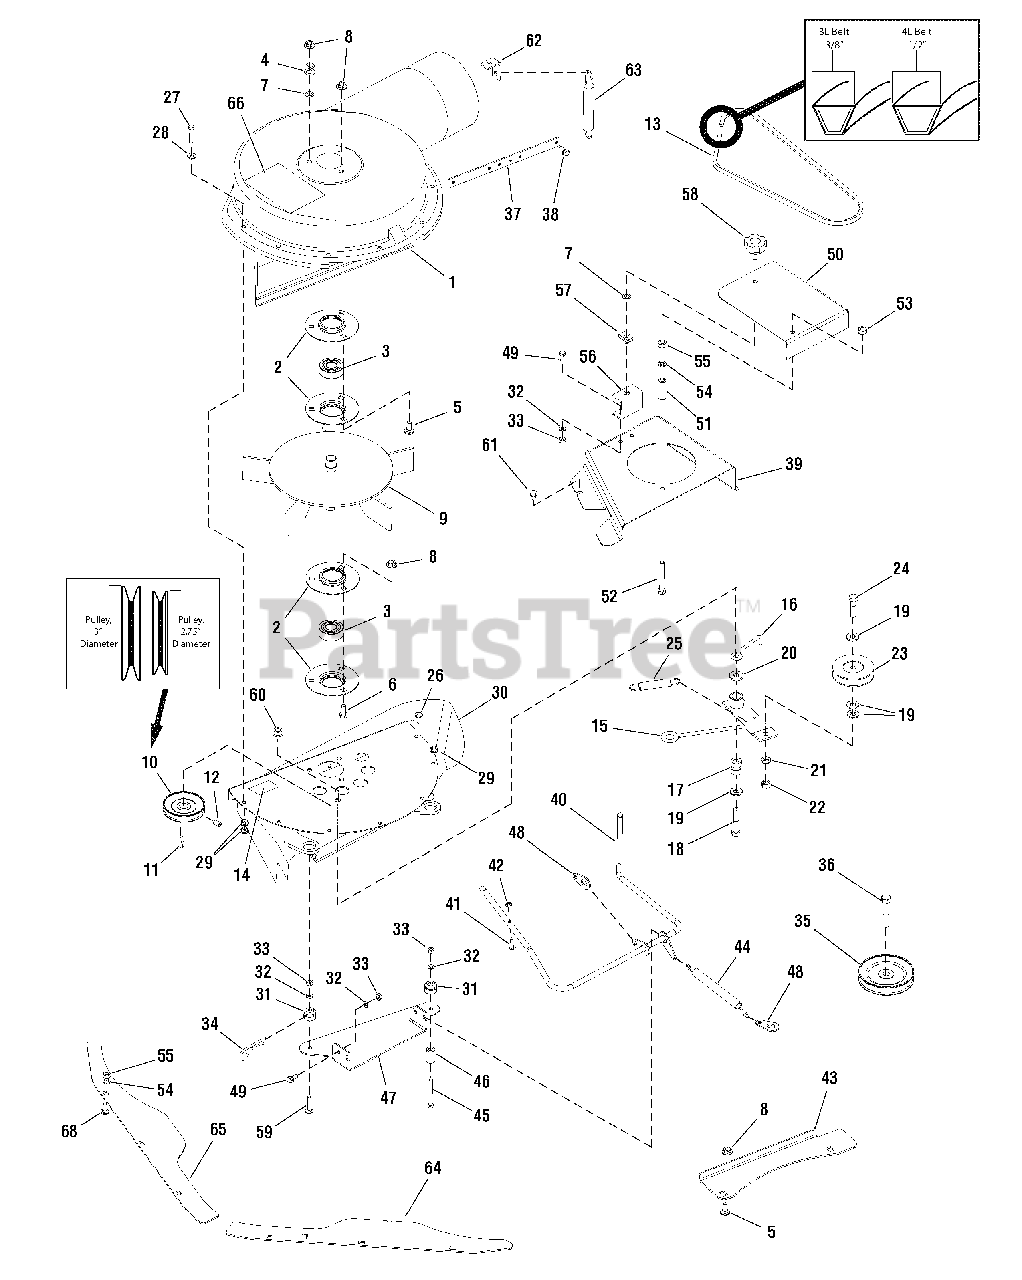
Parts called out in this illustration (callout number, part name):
1	TURBO HOUSING, Fan
2	RETAINER, Bearing
5	BOLT, Carriage, 5/16 - 18 x 3/4
6	CAPSCREW, 5/16 - 18 x 3/4
7	PUSH NUT, 5/16
8	NUT, Flange Lock, 5/16 - 18
9	FAN ASSEMBLY
10	PULLEY, 3" Diam., For 3L Belt
10	PULLEY, 2-3/4" Diam., For 4L Belt
11	KEY, Woodruff, #61
12	SCREW, Set Torx, 5/16 - 18 x 5/16
13	V-BELT, 3L 3/8" x 36.9
13	V-BELT, 4L, 1/2" x 36.9
15	IDLER ARM ASSEMBLY
17	BUSHING
18	CAPSCREW, 3/8 - 16 x 2
19	WASHER, 3/8
20	WASHER, 3/8
21	LOCKWASHER, Spring, 3/8
22	NUT, Hex, 3/8 - 16
23	PULLEY, Idler
24	CAPSCREW, Hex Head, 3/8 - 16 x 1-1/2, G5
25	SPRING, Extension
26	SCREW, Truss Head Phillips, 1/4 - 20 x 3/4
27	CAPSCREW, Hex Head, 1/4 - 20 x 1-1/4, G5
28	WASHER, 1/4
29	NUT, Hex Lock ESNA, 1/4 - 20
30	PLATE ASSEMBLY
31	PIN, Pivot
32	LOCKWASHER, Spring, 1/4
33	NUT, Hex, 1/4 - 20
34	CLIP, Hairpin
35	PULLEY ASSEMBLY
36	CAPSCREW, Hex Head, 7/16 - 14 x 2-1/4, G8
38	SCREW, Hex Washer Head Taptite, 1/4 - 20 x 5/8
39	COVER, Arbor R.H. Turbo
40	ROD & ANCHOR
41	SCREW, Truss Head Phillips, #10 - 24 x 3/4
42	NUT, Nylon Hex Lock, 10-24
43	PLATE, Support
44	SPRING, Extension
45	CAPSCREW, Hex Head, 1/4 - 20 x 2-1/4, G5
46	SPACER
47	PLATE, Deflector
48	TAB, Locking
49	CAPSCREW, Hex Head, 1/4 - 20 x 5/8
52	CAPSCREW, Hex Head, 5/16 - 18 x 2-1/2, G5
53	NUT, Hex Lock ESNA, 5/16 - 18
54	LOCKWASHER, Spring, 5/16
55	NUT, Hex, 5/16 - 18
56	BRACKET, "C"
57	NUT, Speed, 5/16 - 18
58	KNOB, Plastic
59	BOLT, Carriage, 1/4 - 20 x 1-1/4
60	NUT, Hex Two-Way Lock Flange, 3/8 - 16
61	SCREW, Hex Washer Head Taptite, 1/4 - 20 x 3/8
62	BRACKET, "L"
63	SPRING, Extension
64	BAFFLE, Front L.H.
65	BAFFLE, Front R.H.
66	DECAL, Danger Thrown Objects
68	BOLT, Carriage, 5/16 - 18 x 3/4
69	HARDWARE BAG
70	KIT, Pulley & Belt, 54" Turbo
